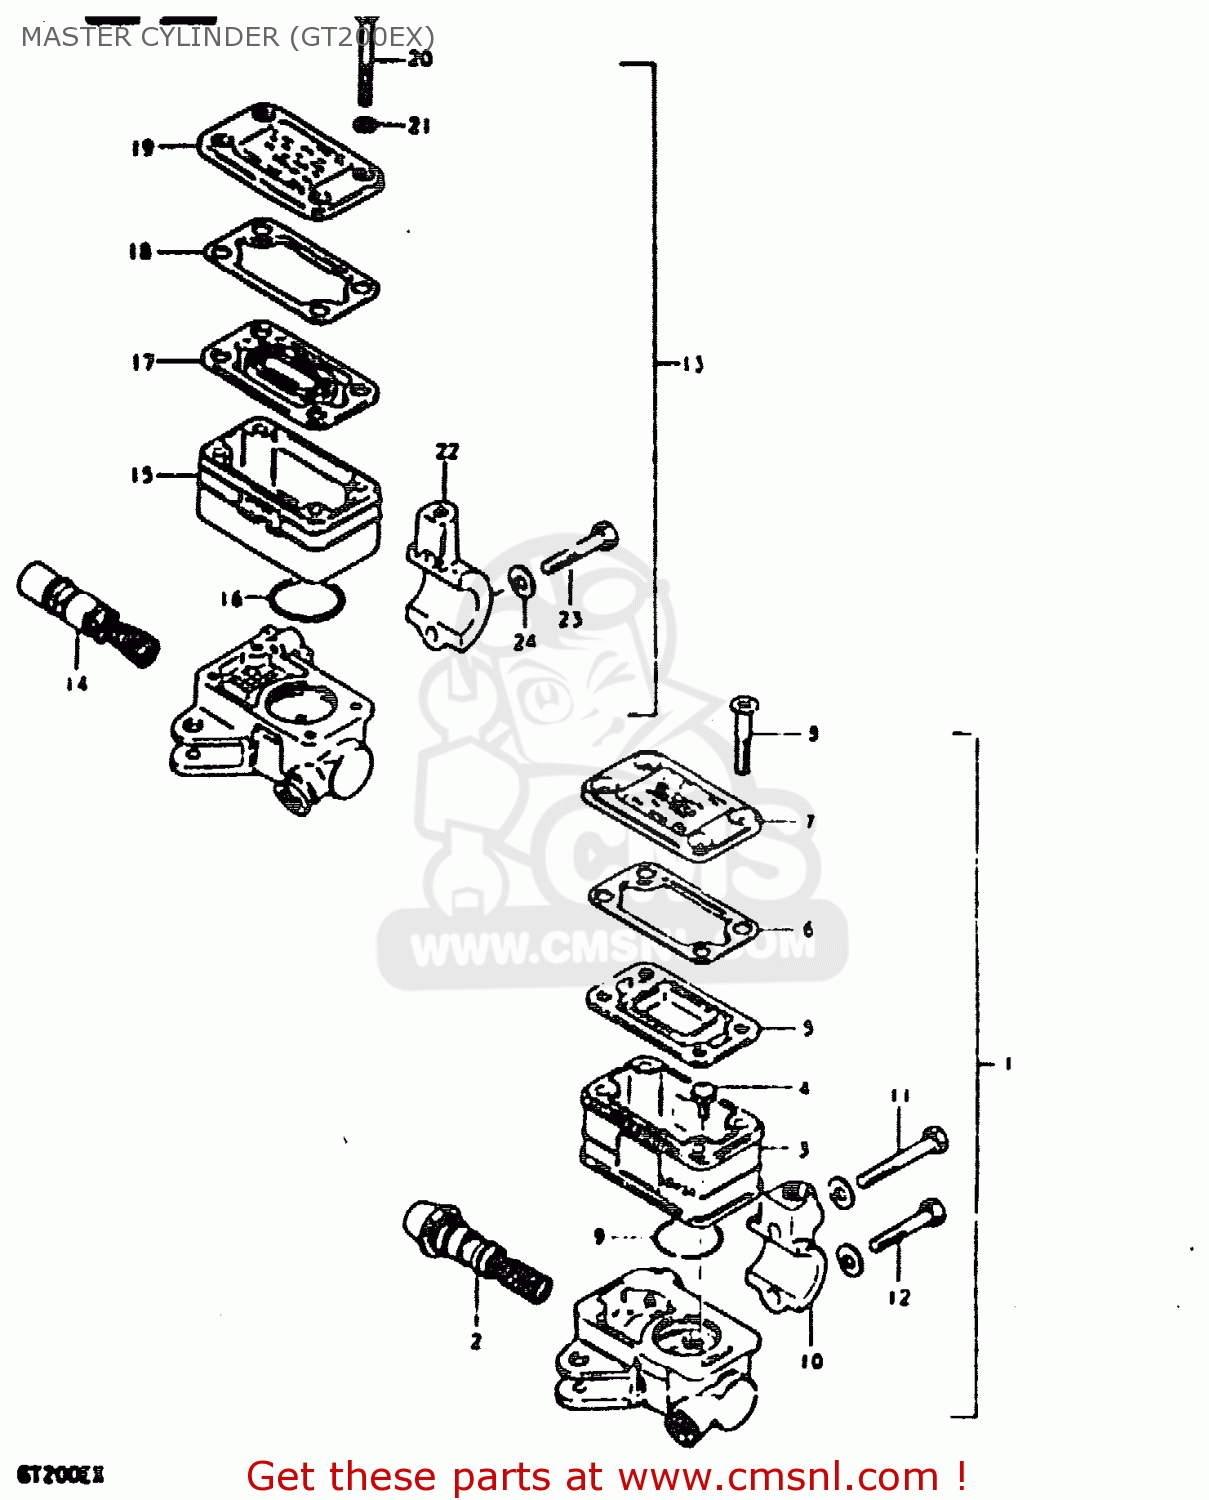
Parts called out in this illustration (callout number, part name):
1	CYLINDER ASSY, MASTER
2	PISTON & CUP SET
3	RESERVOIR
4	SCREW,MASTER C
5	DIAPHRAGM
6	PLATE,DIAPHRAGM
7	CAP
8	SCREW
9	O RING
10	HOLDER
11	BOLT,MASTER CYLINDER H
12	BOLT,MASTER CYLINDER H
13	CYLINDER ASSY, MASTER
14	PISTON & CUP SET
15	RESERVOIR
16	O RING
17	DIAPHRAGM
18	PLATE,DIAPHRAGM
19	CAP
20	SCREW
21	WASHER
22	HOLDER
23	BOLT
24	WASHER
